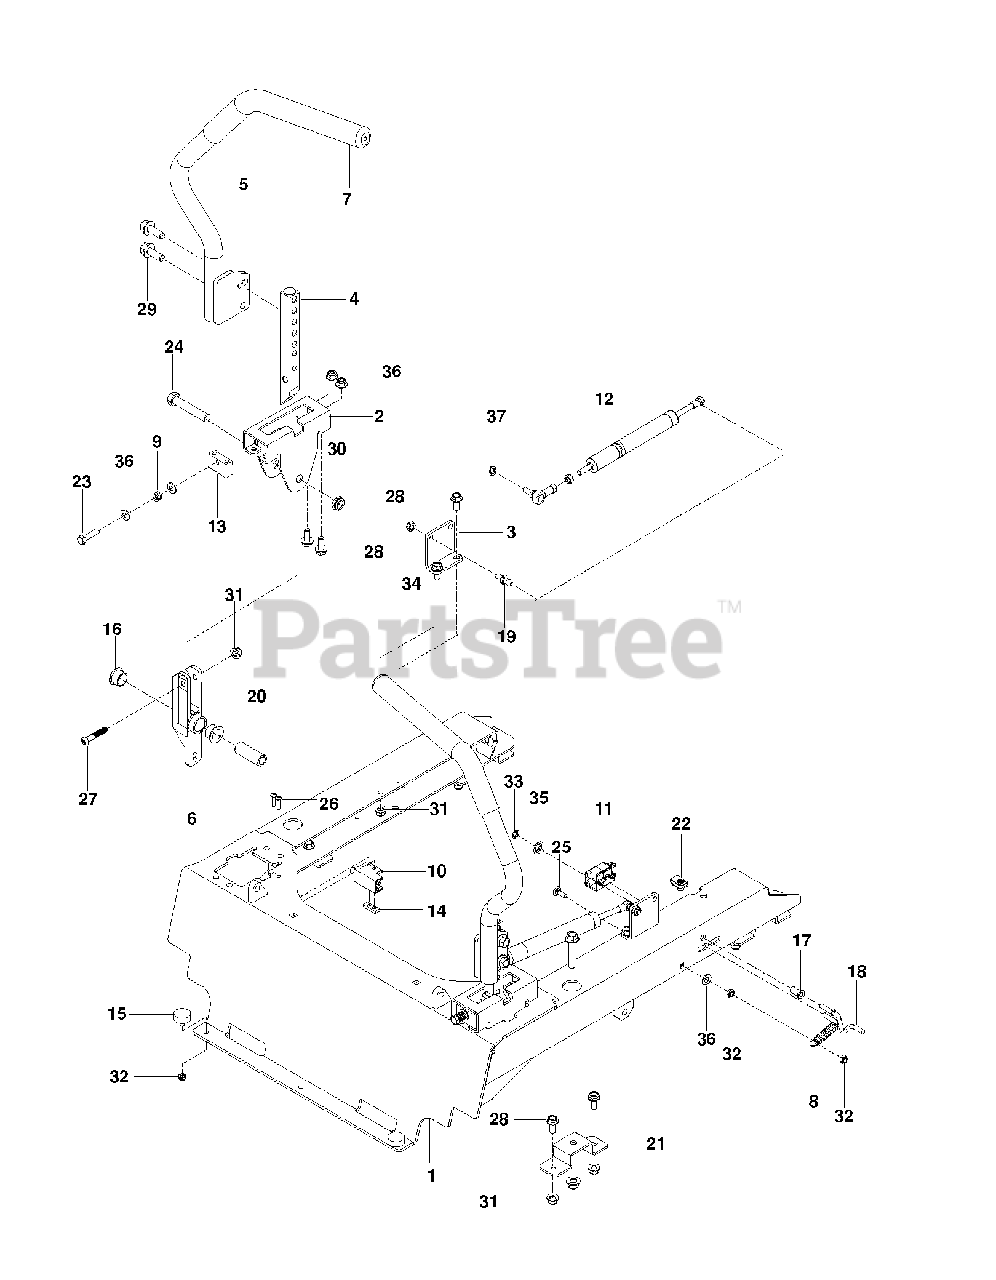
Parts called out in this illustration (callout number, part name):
1	FRAME SEAT MOUNT BLUE
2	BRACKET, CONTROL
4	LEVER, MOTION
8	GRIP - DRIVE LEVER
9	SPRING, EXTENSION
12	SWITCH, BRAKE 3P
13	ASSEMBLY, DAMPENER
14	BLOCK, TRACKING
15	BLOCK, LOWER
16	BUMPER, 1/4-20 STUD, 1/4
17	BEARING, FLANGE
18	BUSHING, 1/4 FLANGE
19	LINK, SWITCH
20	10MM BALL STUD
21	SPACER, PIVOT CONTROL
22	MOUNT, MID-SECTION, BLK
23	U-CLIP 5/16-18 NUT RETAINER
25	HCS 1/2C X 2 3/4
26	RHSNB 1/4C X 3/4
27	SCR #10-24 X .75 SKT HD BLK
29	HHFS 5/16-18 X 3/4
30	HHFS 3/8-16 X 1 GRD 5 ZD
31	NUT 1/2-13 HEX JM NYL
32	5/16-18 NYLOC FLANGE NUT
33	JAM NUT 1/4C
35	NUT 5/16 NYLOC
37	FLAT WASHER 5/16 SAE
